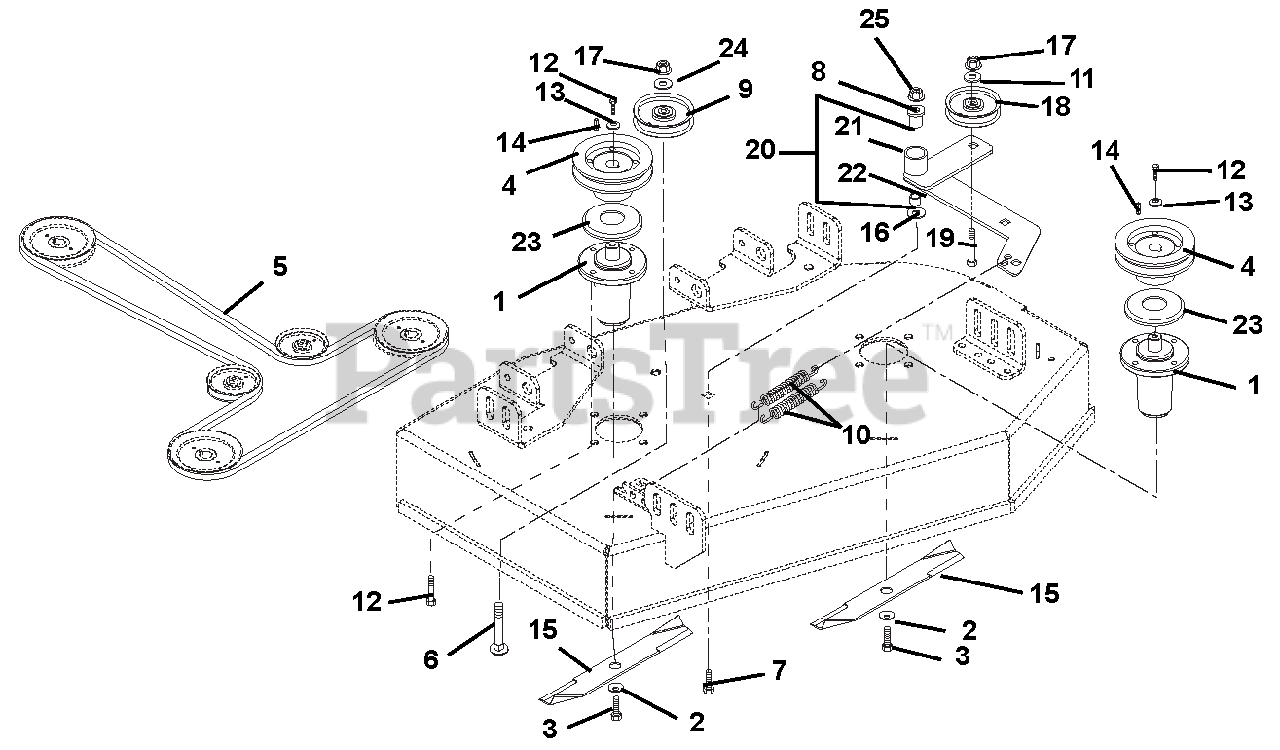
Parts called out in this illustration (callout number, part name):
1	ASM,MAINT FREE SPINDLE
2	WSHR-BLVL .669X1.535X.138
3	BLT-HEX .62-18X1.75 GR8 YWZC
4	SHEAVE, 5.00 SPINDLE (1.000ID)
5	V-BELT, HB-WRAPPED
6	@BLT-RDHDSQNK .38-16X3.00 G5YZ
7	@BLT-RHDSSQNK .50-13X3.50 G5YZ
8	BEARING, PEDESTAL
9	IDLER-FLAT 4.00X.38 (2.00 W)
10	SPRING,EXT TO 08300513
11	WSHR-FL-STL .375X1.125X.065YWZ
12	BLT-HEX .38-16X1.0 GR8 YZ EP30
13	WSHR,FLT STL.406X1.50X.245YWZC
14	KEY, SQ .25X.25X1.00 RC 40-50
15	BLD,MULCHING 50" MWR
16	@WSHR-FL-STL.563X1.38X.109YWZC
17	@NUT-LK-NYL-FLG .38-16 YWZC
18	IDLER, FLAT 4.00 X .38 (1.OOW)
19	@BLT-RDHDSQNK .38-16X2.00 G5YZ
20	ASSM, IDLER ARM PIVOT
21	WMT, IDLER PIVOT ARM
22	BSHG, 1.00 X 1.125 X 1.937
23	SLINGER, DUST
24	SEAL, IDLER BEARING
25	@NUT-LK-NYL-FLG .50-13 YWZC
